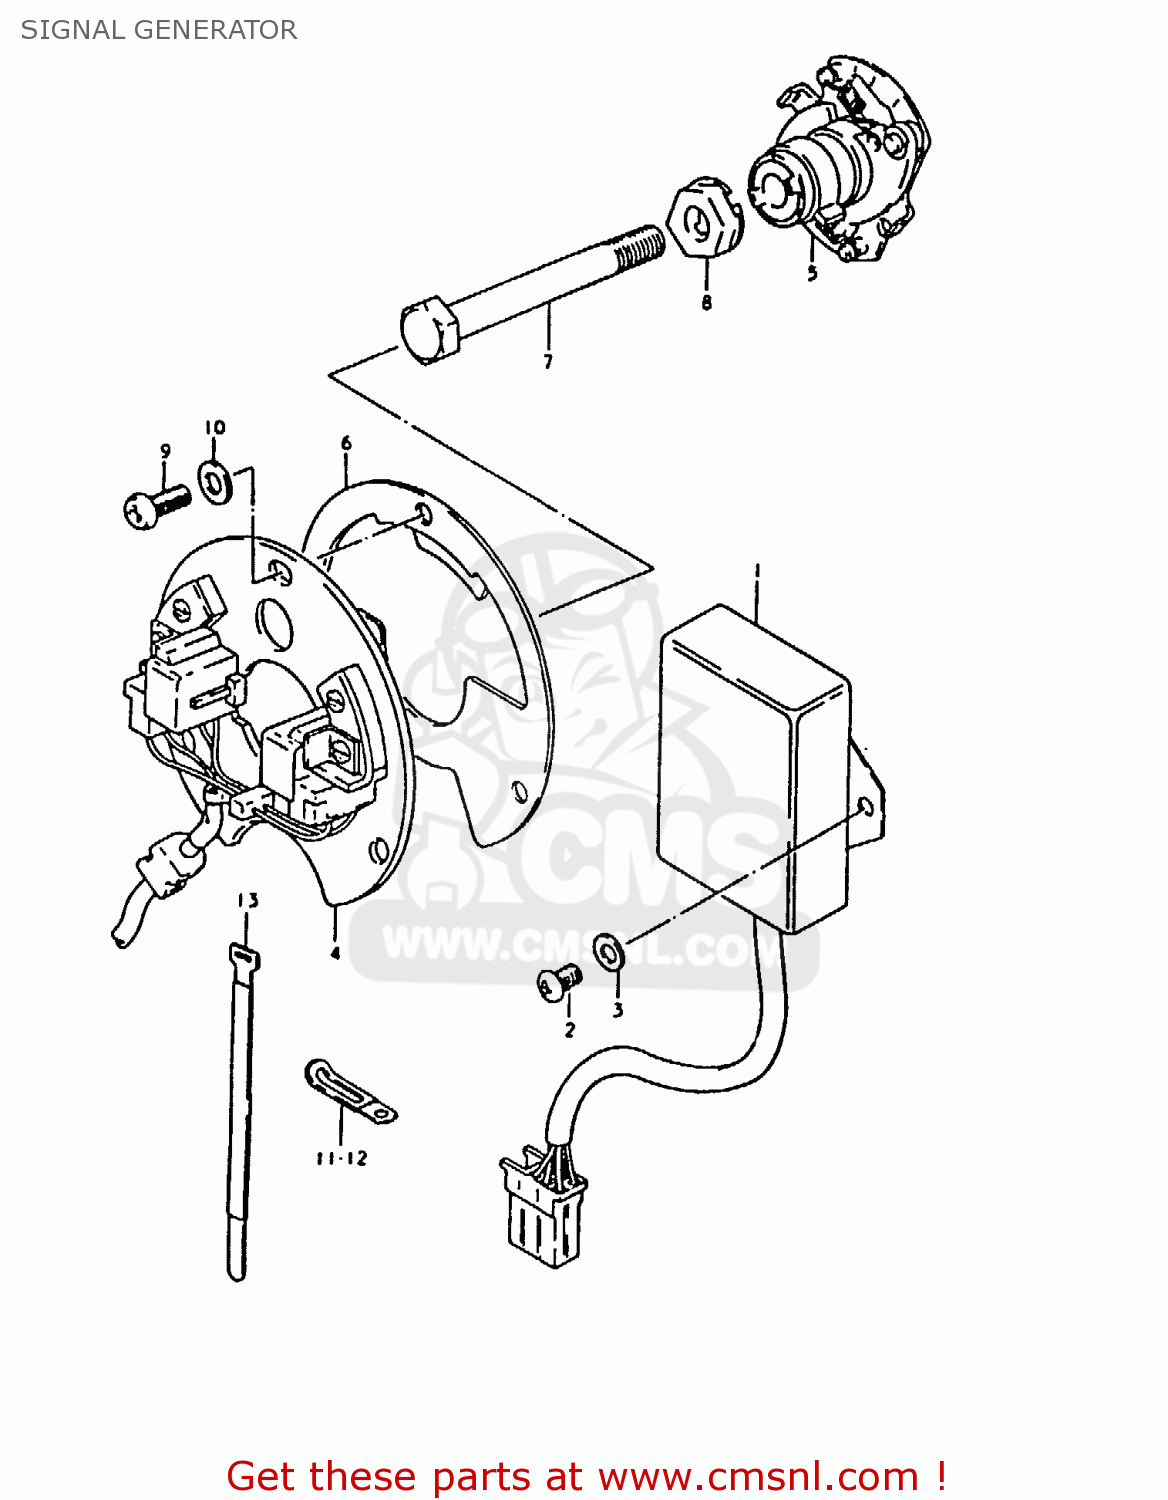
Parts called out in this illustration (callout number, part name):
1	IGNITER UNIT
2	SCREW
3	WASHER
4	SIGNAL GENERATOR ASSEMBLY
5	GOVERNOR ASSEMBLY
6	PLATE,TIMING
7	BOLT
8	WASHER
9	SCREW(5X12)
10	WASHER
11	CLAMP L:35
12	CLAMP
13	CLAMP
